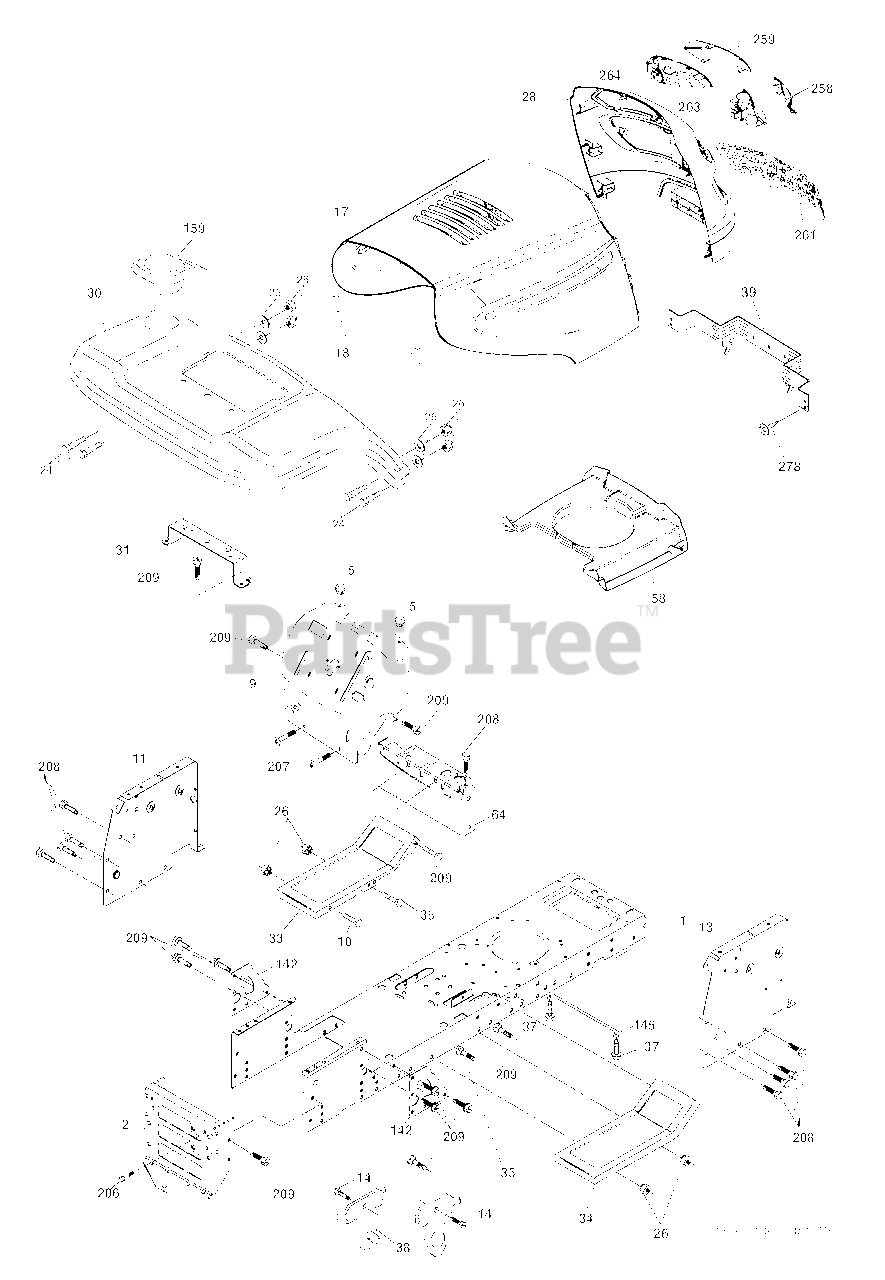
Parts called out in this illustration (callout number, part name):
2	Drawbar
14	Hood
15	Lens Grille LH
18	Grille
25	Lens Grille RH
58	Air Duct
68	Screw THDROL 5/16-18 x 1/2
99	Rod Bypass Asm
130	Screw 10 x 3/4 Single Lead-Hex
137	Bumper Hood
138	Cupholder
150	Duct Heat Hood
151	Bracket Pivot
152	Shield Browning/Debris
159	Screw Hexwsh Thdrol 3/8-16 x 3/4
162	Screw Hex Wsh Hi-Lo 1/4 x 1/2 UNC
175	Crossmember
176	Screw 10-24 x 5/8 Wshd Qdrx
177	Bushing Steering
181	Bushing Mtg. Fender Crgo.
182	Dash Lower
183	Bolt Fin Hex 5/16-18 x 1-1/4
184	Spacer Fender
189	Screw 5/16-18 x 3/4
194	Nut Lock Hex Flange 5/16-18
196	Console Asm. Deck Lift
197	Rod Pivot Chassis
207	Bezel RH
208	Bezel LH
219	Stud Fastener
222	Screw thd Roll 1/4-20 x 5/8
229	Screw 3/8-16 x 1
230	Bolt Shoulder 5/16-18
230	Plug Cruise/Hook/Phone
